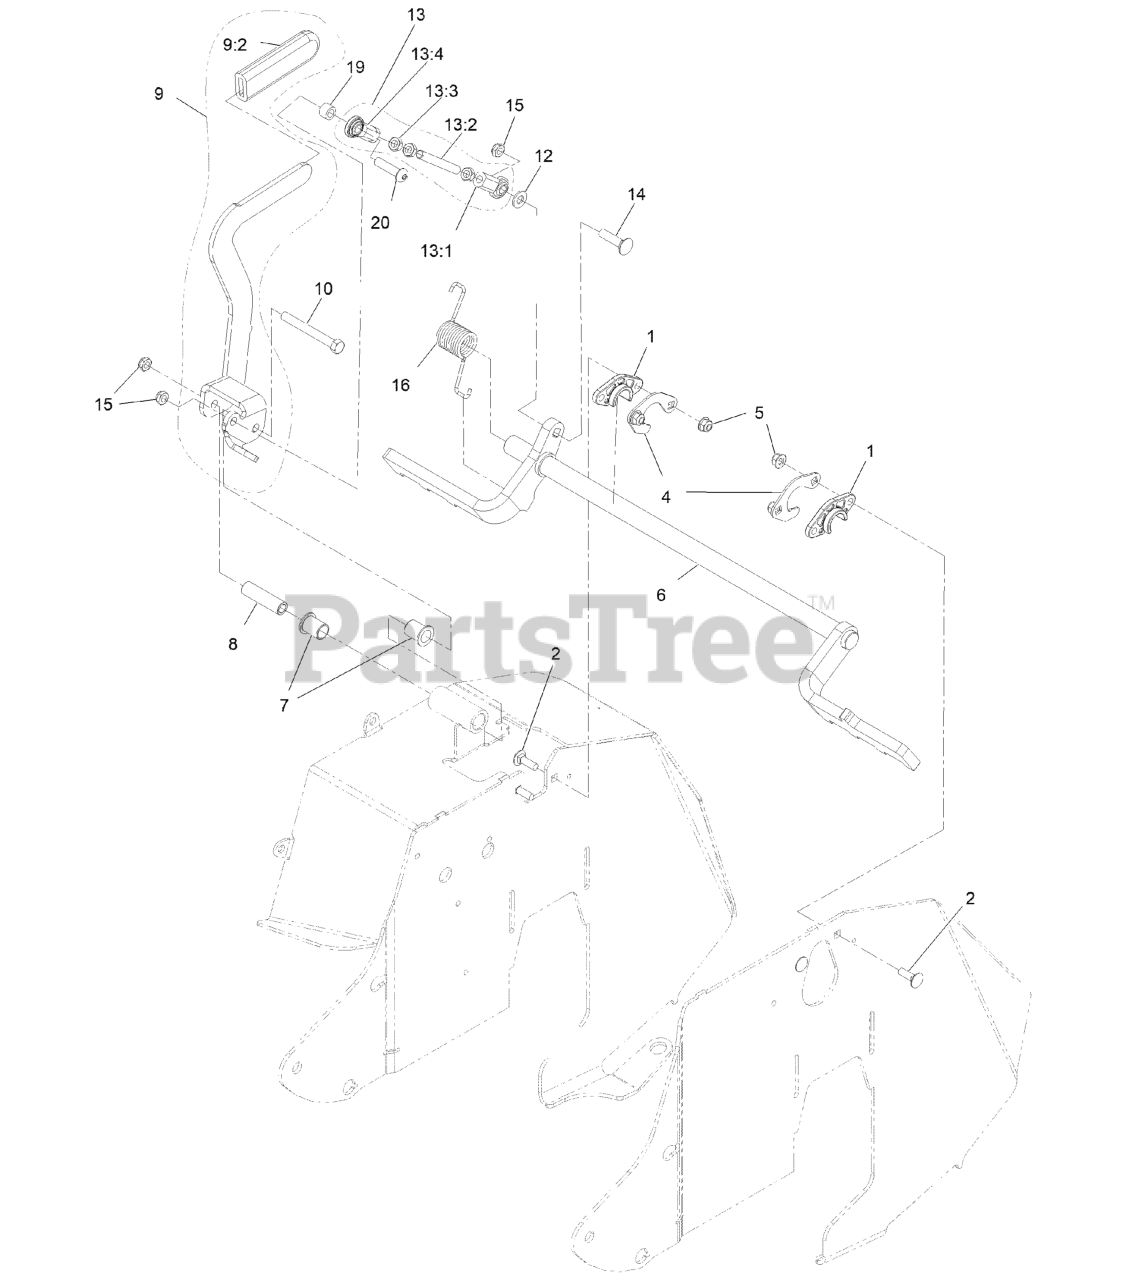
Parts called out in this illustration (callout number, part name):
1	BUSHING-FLANGE
2	BOLT-CARR
4	SUPPORT, BEARING
5	NUT-HF, NI
6	WLD-BRAKE SHAFT 32/36
7	BUSHING-FLANGE
8	SPACER, BRAKE PIVOT
9	ASM, LEVER W/ GRIP
9:2	GRIP-LEVER
10	SCREW-HH
12	WASHER-FLAT
13	ASM, BRAKE LINK
13:1	JOINT-BALL, END
13:2	LINKAGE, BRAKE
13:3	NUT-HJ
13:4	JOINT-BALL END, LH
14	SCREW-CARR
16	SPRING-TORSION
20	Screw-HSBH
